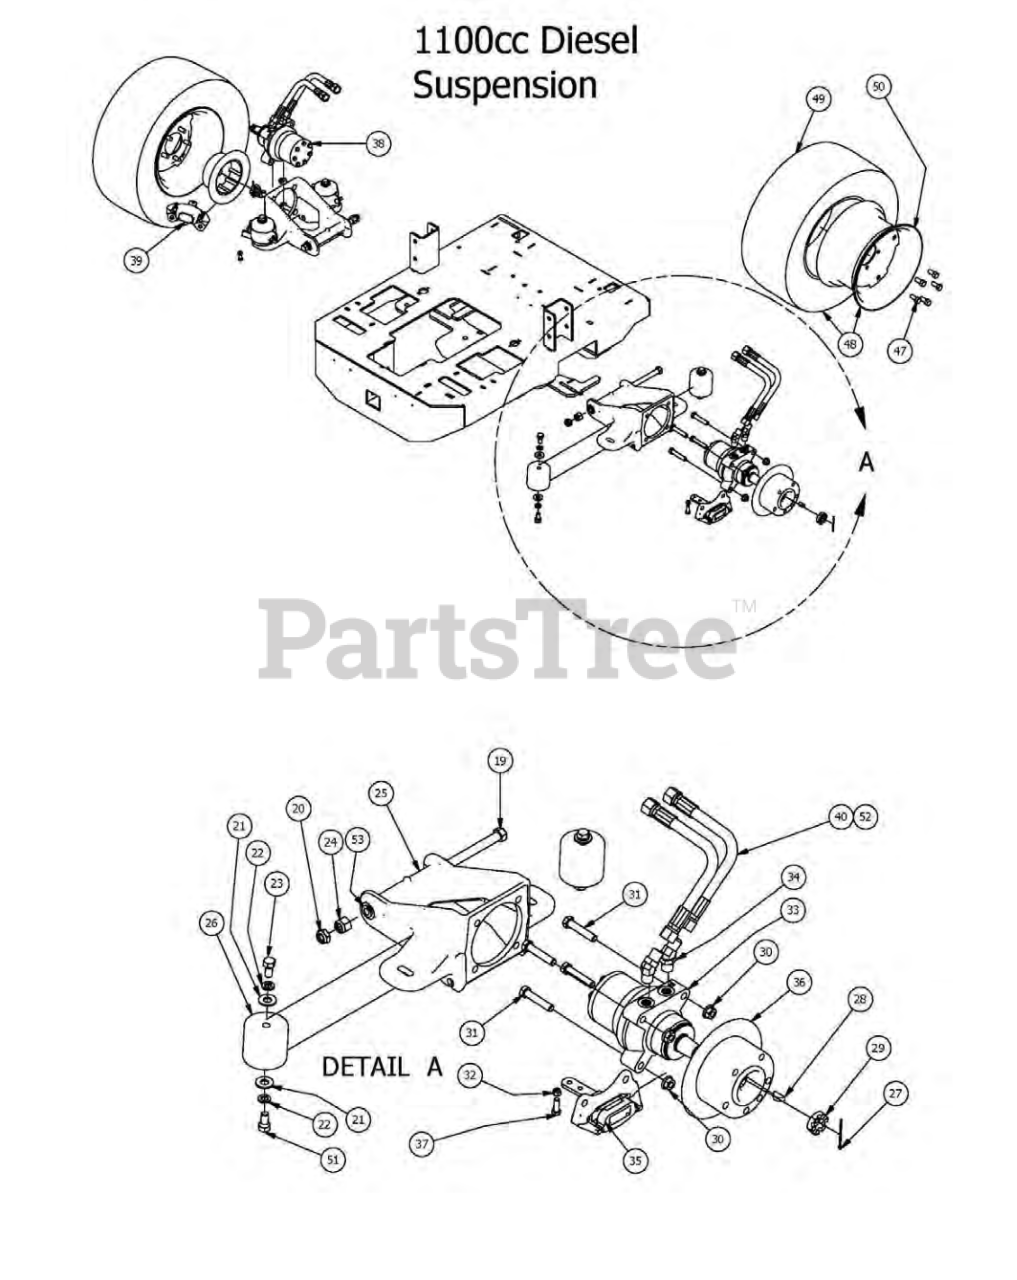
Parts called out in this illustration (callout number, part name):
1	Diesel Back Pump Cover 2008 Bottom
2	Back Cover Hinge Bracket
3	Diesel Back Pump Cover 2008 Top
4	Diesel Hood 3 Cyl
5	5/16" x 1" Carriage Bolt
6	.360 ID Plastic Washer
7	1/4" x 5/8" BS C/S 18-8 SS
8	5/16-18x3/4 carriage bolt
9	5/16" Flange Nut
10	1/4 Nylock Nut
11	5/8 Round Insert
12	5/16" x 1" Bolt
13	5/16-18 Nylock Insert Locknut
14	5/16" Knob
15	5/16" x 1 1/4" Carriage Bolt
16	1/4" x 1 1/2" Self Tapping Screw
17	1/4" Flat Washer
18	8" Rubber Bumper
19	5/8"x10" Hex Bolt (Grade8)
20	5/8" Nylock (1/2 Jam)
21	1/2" Washer (Grade 8)
22	1/2" Lock Washer
23	1/2" x 1" Hex Bolt
24	5/8 Std NC Nylock Nut
25	60 Suspension kit Wheel Motor
26	Vibration Mount-Blue Dot
27	1/8x2-1/4 cotter pin Zinc
28	Woodruff Key
29	1" Cas de Nut for Wheel Motor
30	1/2" Flange Nut
31	1/2" x 2 1/2" Hex Bolt
32	5/16-18 Nylock Insert Locknut
33	18cc Parker Wheel Motor- Right
34	45 Degree Wheel Motor Fitting -6802-10-10
35	XP/AOS Right Brake Caliper
36	Brake Disk
37	3/8" x 1" Hex Bolt
38	18cc Parker Wheel Motor- Left
39	XP/AOS Left Brake Caliper
40	26" Hose Assembly with Adaptors
41	5/8" x 2 1/2" Grade 5 Hex Bolt (Coarse)
42	5/8 Std NC Nylock Nut
43	5 V Idler Pulley-BCVI-81
44	5/8" x 1/" Collar W/One Set Screw
45	Steel Pump Cover Latch
46	10-24 X 5/8 BS Button Head Bolt
47	1/2-20 x 1-1/2 Lug Bolts Zinc
48	26 x 12.00-12 Tire and Orange Wheel Assembly
49	26x 12.00-12 Tire
50	12 x 10.5 Wheel AOS Rear
51	1/2-13 1-1/4 Hex bolt
52	26" Hose Only
53	Brass Bushing
54	10-24 Nylock Locknut
